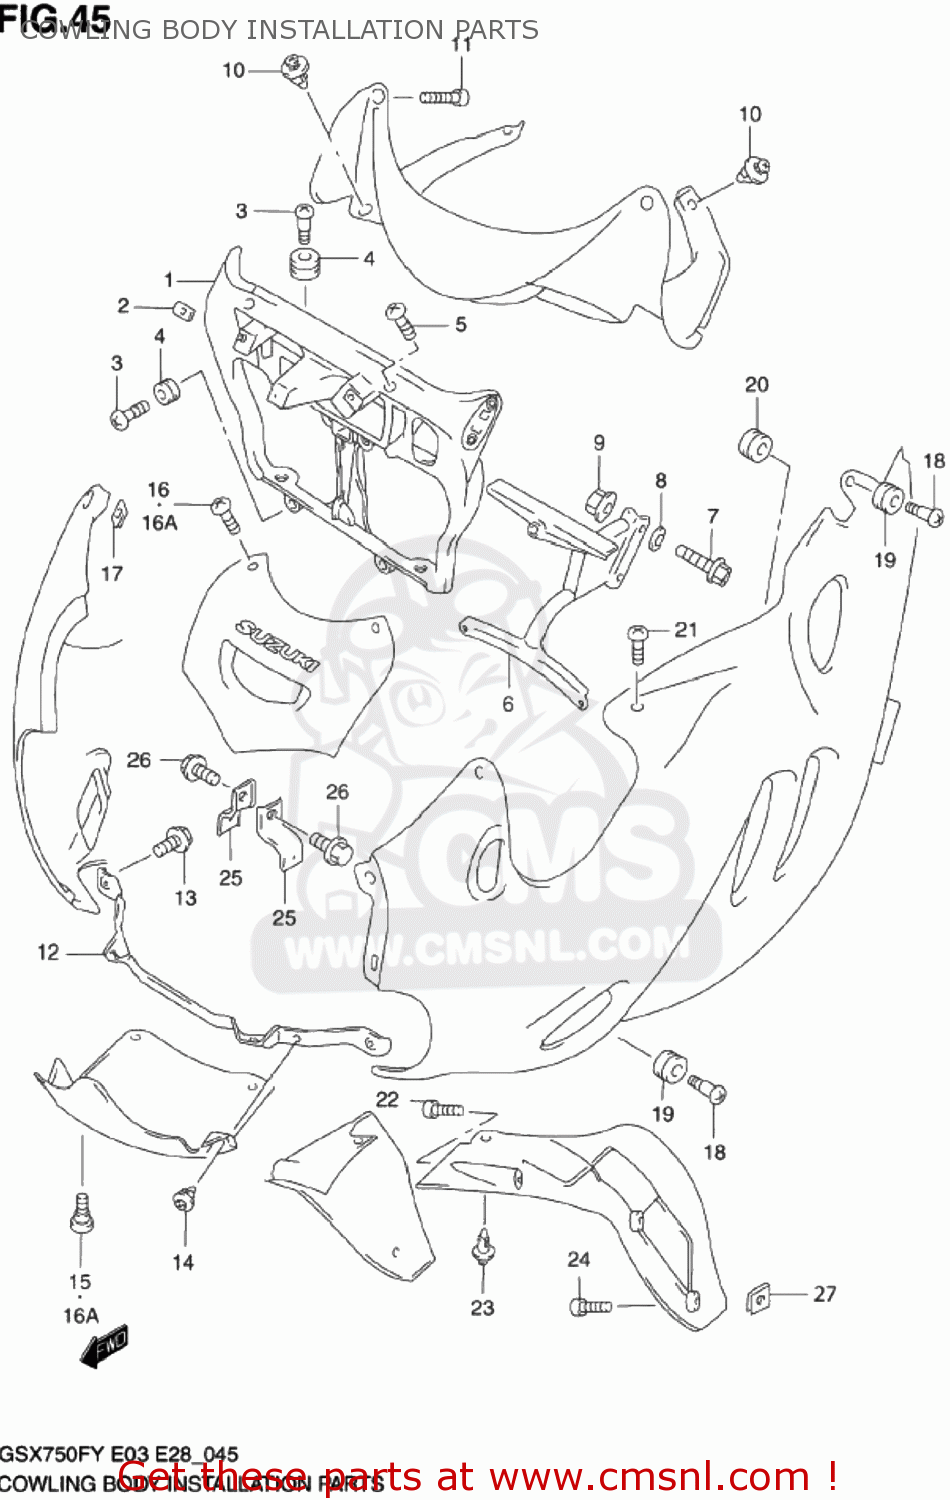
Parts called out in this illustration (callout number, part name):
1	BRACE,COWLING FR
2	NUT,COWL
3	SCREW(6X20)
4	CUSHION
5	SCREW
6	BRACE,COWLING RR
7	BOLT(8X40)
8	WASHER
9	NUT
10	CLIP(BLACK)
11	SCREW
12	BRACKET,PANEL CTR LWR
13	BOLT
14	CLIP(BLACK)
15	SCREW(5X14)
16	SCREW(5X14)
16A	SCREW(5X16)
17	NUT
18	SCREW(6X20)
19	CUSHION
20	CUSHION
21	SCREW(5X16)
22	SCREW(4X10)
23	CLIP(BLACK)
24	SCREW
25	BRACKET,COWLING SIDE LWR
26	BOLT 6X12
27	NUT
